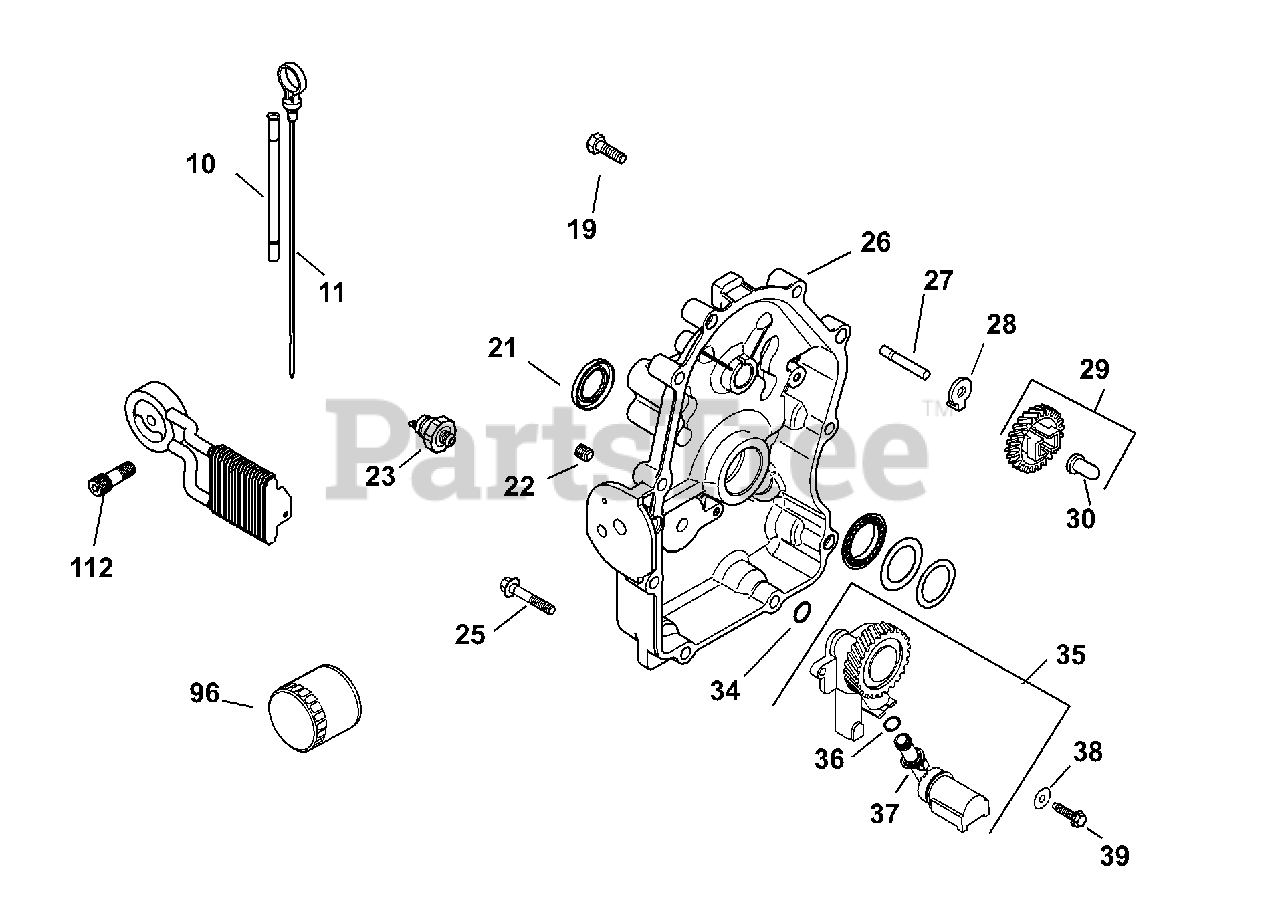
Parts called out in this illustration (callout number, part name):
10	Kit, Dipstick/Dipstick Tubes
19	Screw, Flg M8X1.25X45
22	Plug, Pipe CTSK 1/8"
23	Switch, Oil Pressure
25	Screw, Flg M8X1.25X45
26	Plate, Closure & Bearing
27	Shaft, Governor Gear
29	Kit, Governor Gear w/Pin
30	Pin, Governor Regulating
35	Kit, Oil Pump Assy
36	O-Ring, Oil Pick-Up
37	Pick-Up, Oil
38	Washer, Flat 1/4" (O.D. 5/8")
39	Screw, Thread Forming
112	Nipple, Oil Filter
